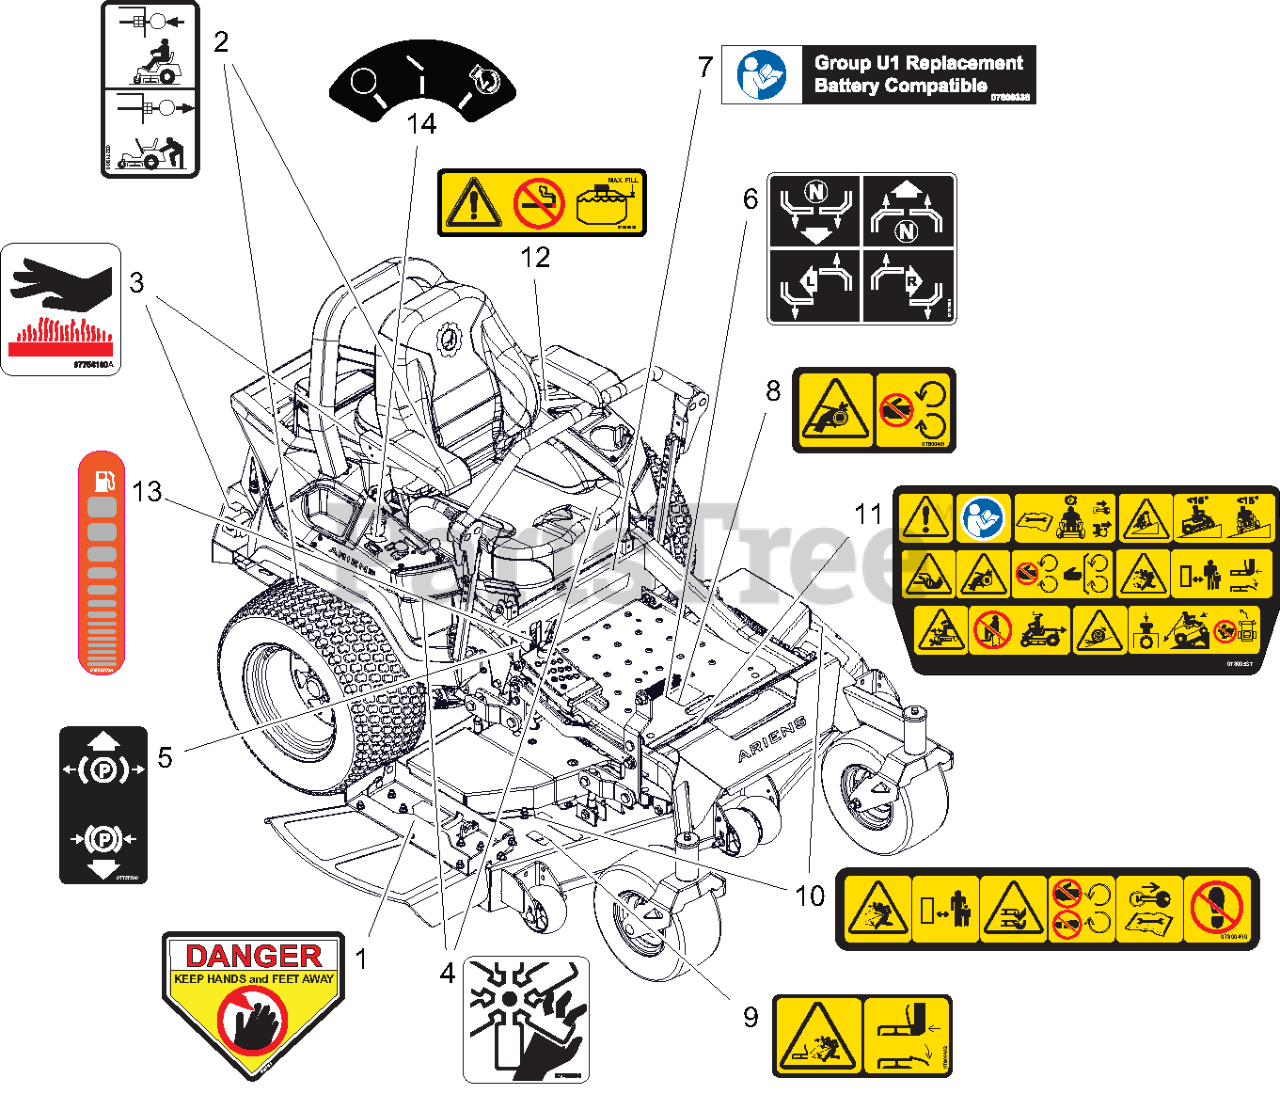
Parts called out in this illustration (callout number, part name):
1	DECAL, DANGER
2	DECAL, TRANSMISSION DISCONNECT
3	DECAL, HOT SURFACE
4	DECAL, DANGER FAN
5	DECAL, PARKING BRAKE LEVER
6	DECAL, INSTRUCTIONAL-STEERING
7	DECAL, U1 BATTERY REPLACEMENT
8	DECAL, SAFETY - GUARDING
9	DECAL, SAFETY - DECK GUARDING
10	DECAL, DECK SAFETY
11	DECAL, MAIN SAFETY
12	DECAL, FUEL WARNING
13	DECAL, ARIENS FUEL LEVEL
14	DECAL, KEYSWITCH
